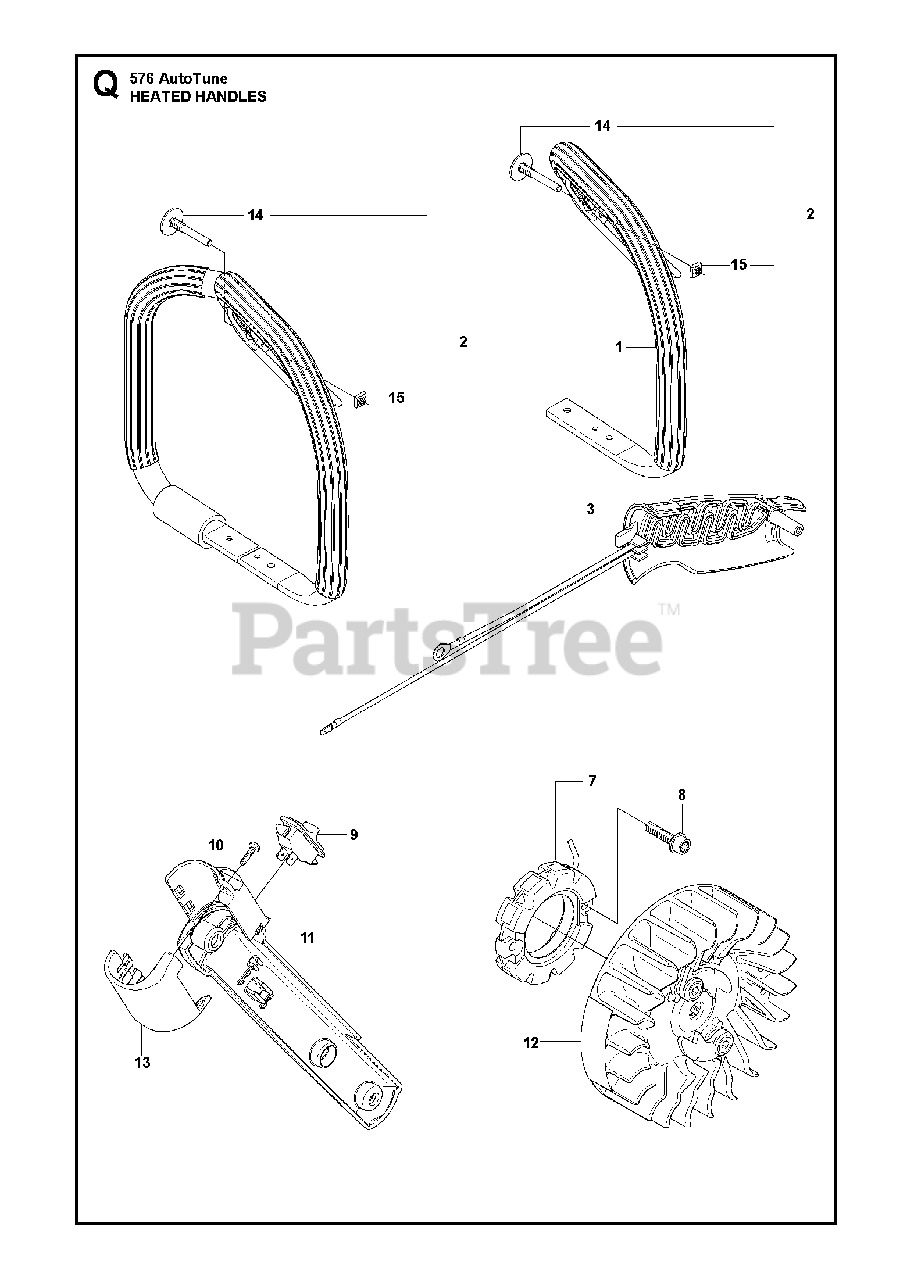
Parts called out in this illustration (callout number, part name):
1	HANDLE (G)
2	HANDLE (WAG)
7	GENERATOR STATOR
14	SCREW
15	NUT
